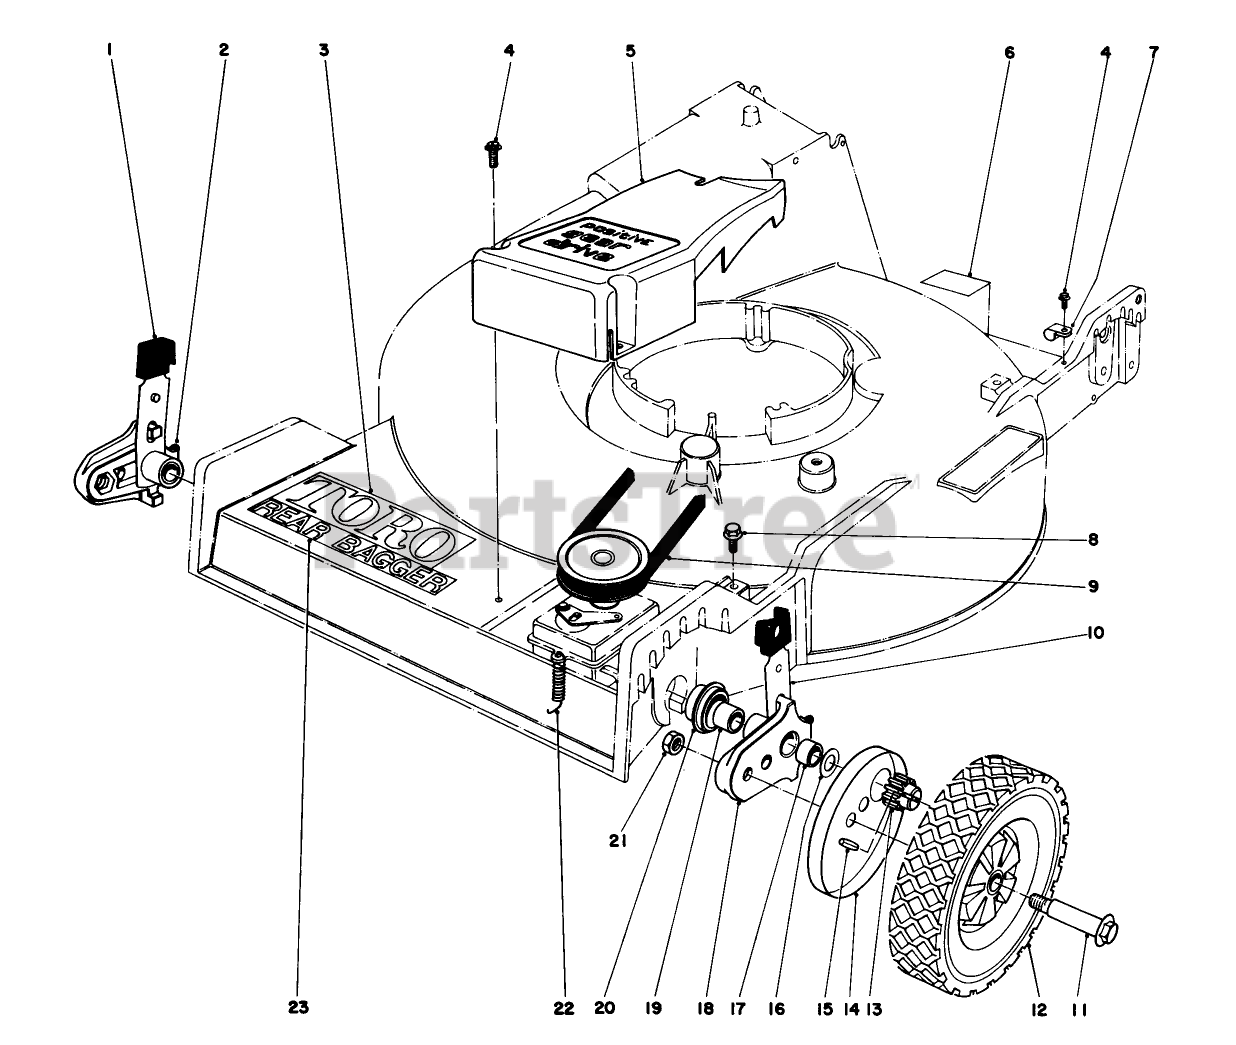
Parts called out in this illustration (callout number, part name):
1	KNOB-ARM
2	FITTING-GREASE
3	TORO LOGO DECAL
4	SCREW
6	Greasing Sticker
7	CLAMP-NYLON
8	SCREW-THD ROLL, HWH
9	BELT-V
11	BOLT-WHEEL
16	WASHER-THRUST
18	PIVOT ARM ASM
19	Bushing
20	END CAP
22	TENSION SPRING
